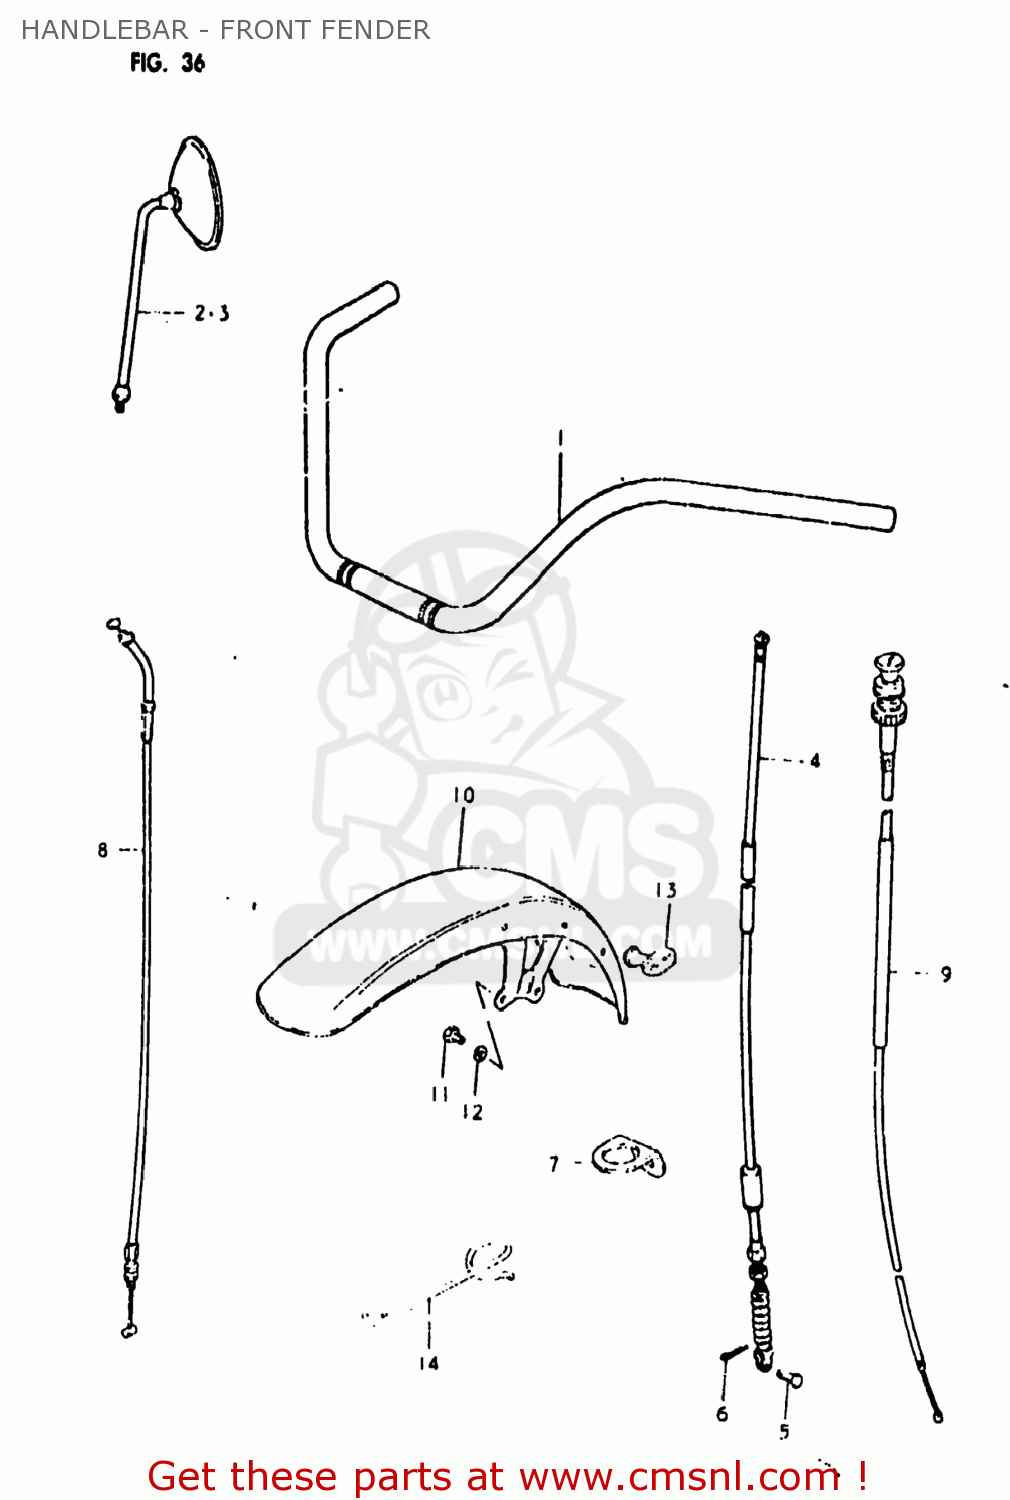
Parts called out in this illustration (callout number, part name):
1	HANDLEBAR
2	MIRROR ASSEMBLY,REAR VIEW
3	MIRROR ASSEMBLY,LEFT
4	CABLE,CLUTCH
5	PIN(L:15)
6	PIN
7	GUIDE,BRAKE HOSE
8	CABLE ASSEMBLY,THROTTLE
9	CABLE ASSEMBLY,STARTER
10	FENDER,FRONT
11	BOLT
12	LOCK WASHER
13	GUIDE,CABLE
14	GUIDE,CLUTCH CABLE
